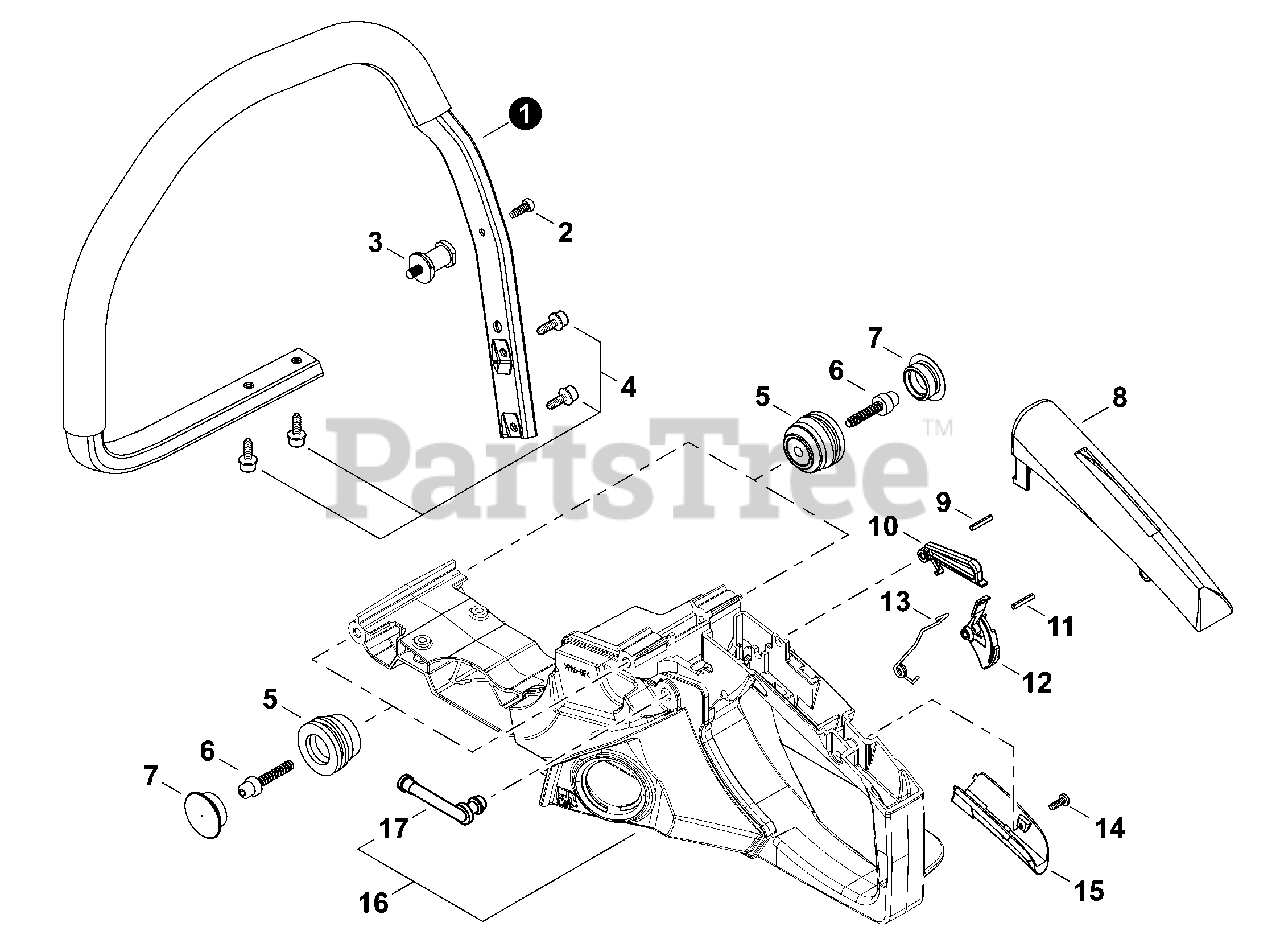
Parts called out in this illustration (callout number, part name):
1	HANDLE, FRONT
2	BOLT M4×14
3	CUSHION 5
4	BOLT, TAPPING M5×16
5	CUSHION
7	CAP, CUSHION
8	COVER, HANDLE
9	PIN, SPRING Ø4×22 MM
10	LOCKOUT, THROTTLE
11	PIN, SPRING Ø4×25 MM
12	TRIGGER, THROTTLE
13	SPRING, THROTTLE RETURN
14	SCREW, TAPPING M4×22
15	GRIP, LOWER
16	HANDLE ASSY, REAR
17	PIPE, FUEL VENT
